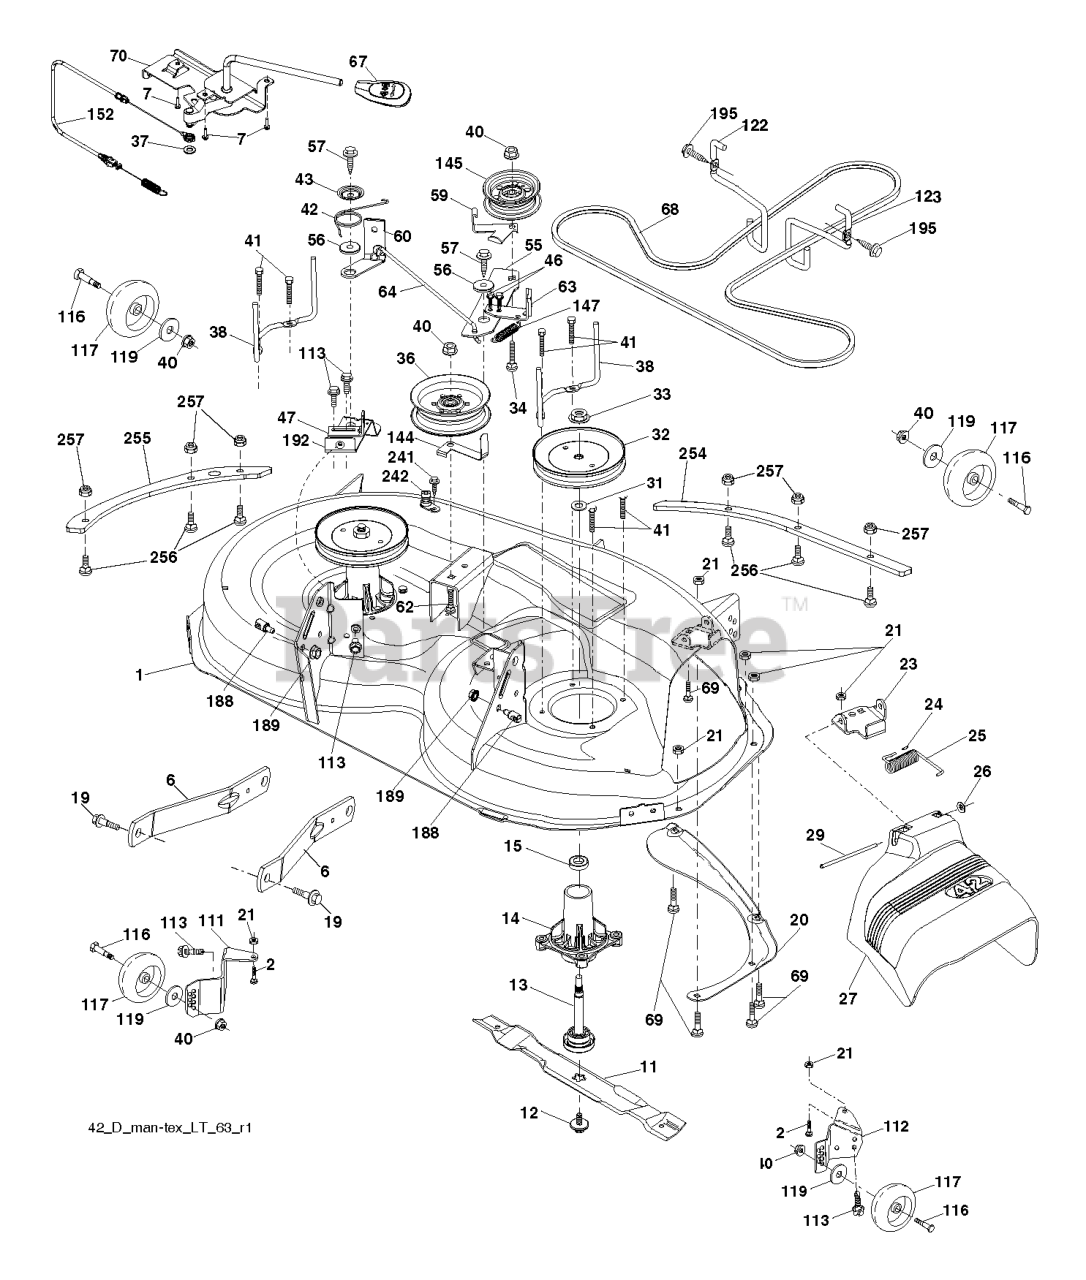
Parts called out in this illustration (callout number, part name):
1	DECK.SVC 42" 196495
1	DECK.SVC.42"2GW
2	BOLT 5/16C X 3/4" CARRIAGE
6	ARM.SUSPENSION.MOWER.R
7	SCREW.#10 X 0.750.BOS
11	42" HI-LIFT BLADE
12	BOLT.WASHER.ASM.7/16-2
12	SCREW.SEMS.7/16-20X1.HEX.HEAD
13	KIT.MANDREL.NONGREASE.TALL
14	RP.HOUSING.MANDREL.4PT.
15	BEARING.MANDREL.TOP.EXTENDED
15	BEARING
19	BOLT.SHOULDER
20	BAFFLE.VORTEX
21	LOCKNUT
23	BRKT.DEFLECTOR.38"2005+
24	CAP-SLEEVE LT
25	SPRING.TORSION.DEFLECT
26	NUT PUSH M
27	SHIELD.DEFLECTOR.MOWER.42"BLAC
29	ROD.HINGE
31	WASHER.SPACER.MANDREL
32	PULLEY.MANDREL.5.438.PD
33	NUT.FLANGE.LOCK.TOP
34	BOLT.3/8-16X1.50
36	PULLEY.IDLER.2006
37	WASHER
38	KEEPER.BELT.MANDREL.PULLEY
40	NUT LOCK FLG 3/8-16 UNC
41	BOLT.HEX.WASHR.HED.313-18X1.19
42	SPRING.TORSION.BRAKE
43	SRPING.TORSION.RETAINE
46	SCREW.1/4-20X5/8
47	BRKT.CLUTCH.CABLE
55	IDLER.ARM.42"
56	SPACER.RETAINER
57	SCREW 3/8-16X1
59	GUARD, BELT
60	ARM BRAKE MOWER
63	ARM BRAKE MOWER
64	LINKAGE.BRAKE.ASM.ZINC
67	HANDLE.CLUTCH.CABLE.LT
68	BELT.DECK.DRIVE.42"
69	BOLT
70	CLUTCH.ASM.MANUAL.YT.PREDATORQ
111	BRKT.WHEEL.GAUGE.LH.42"
112	BRKT.WHEEL.GAUGE.RH.42"
113	BOLT.5/16HEX.WHS.HD
116	Bolts
116	BOLT M
117	WHEEL.GAUGE.RALLY.NARROW
117	WHEEL.GAUGE.RALLY
119	WASHER.5/16.FLAT.STE.STD.
122	KEEPER BELT ENGINE LH
123	KEEPER BELT RH
144	KEEPER.BELT.MOWER
145	PULLEY.IDLER.48"PRIMARY
147	RETURN SPRING
152	CABLE.CLUTCH.CABLE.W/SPRING
152	CABLE.MECHANICAL.CLUTCH
188	STUD.FASTNER.W/ANTI-ROTATE
189	NUT LOCK HEX FLANGE 5/16-18
192	BRKT.BRAKE.STAND.LH.
195	SCREW, 3/8-16X3/4
241	SCREW.TT.#10-32X.5.3/8.FLANGE
242	PORT.WASHOUT
254	PLATES.RENFRC.42DECK.PT431FRNT
255	PLATES.RENFRCE.42DECK.X431SIDE
256	RHSNB, 1/4-20 X 1, GR5
257	NUT T
